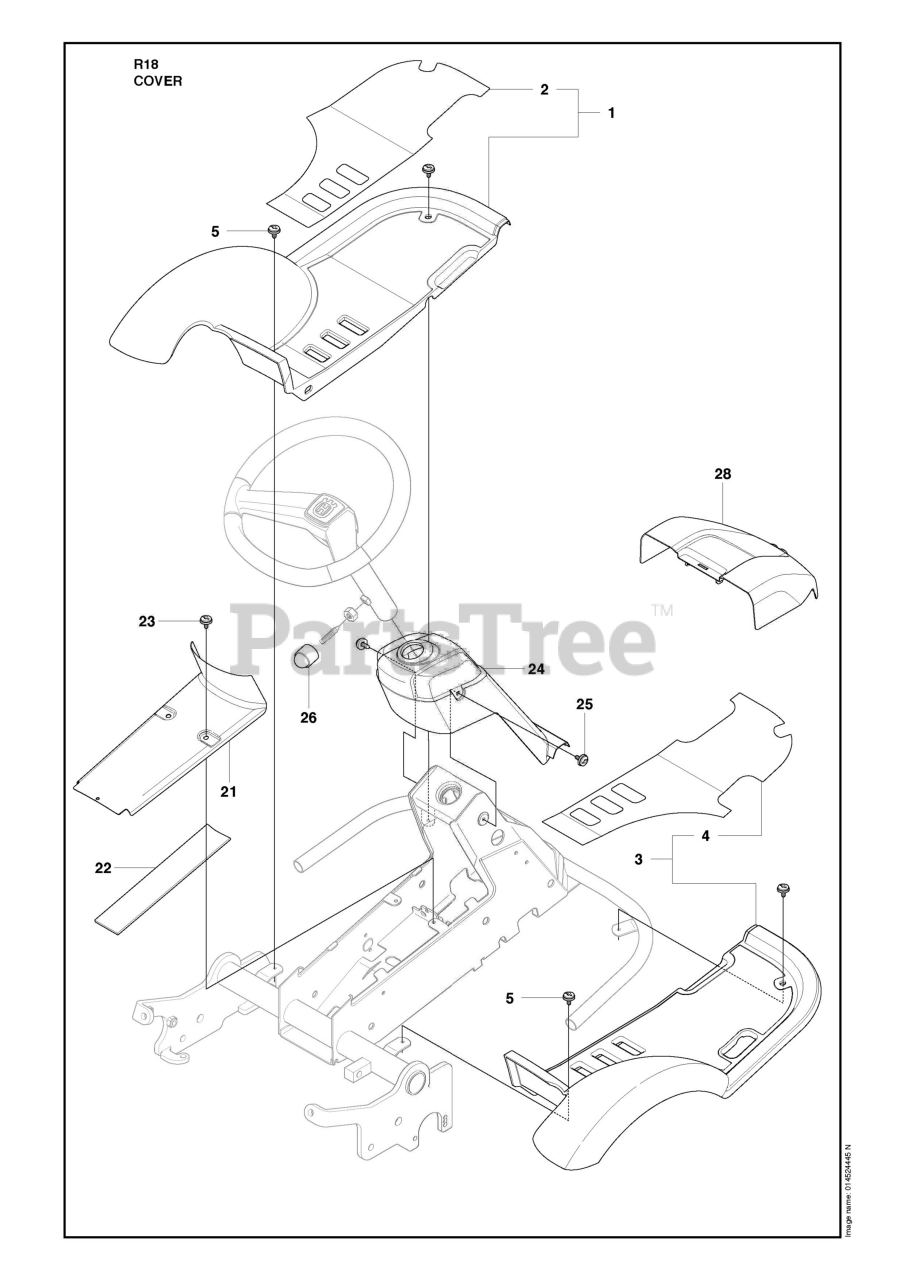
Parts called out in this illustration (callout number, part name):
1	FOOT PLATE
3	FOOT PLATE
6	ENGINE HOOD ASSY
10	ENGINE HOOD ASSY
13	CONTROL COVER
15	CONTROL COVER
19	COVER
26	PROTECTIVE COVER
27	CLIP GRAY
28	UNIT COVER
